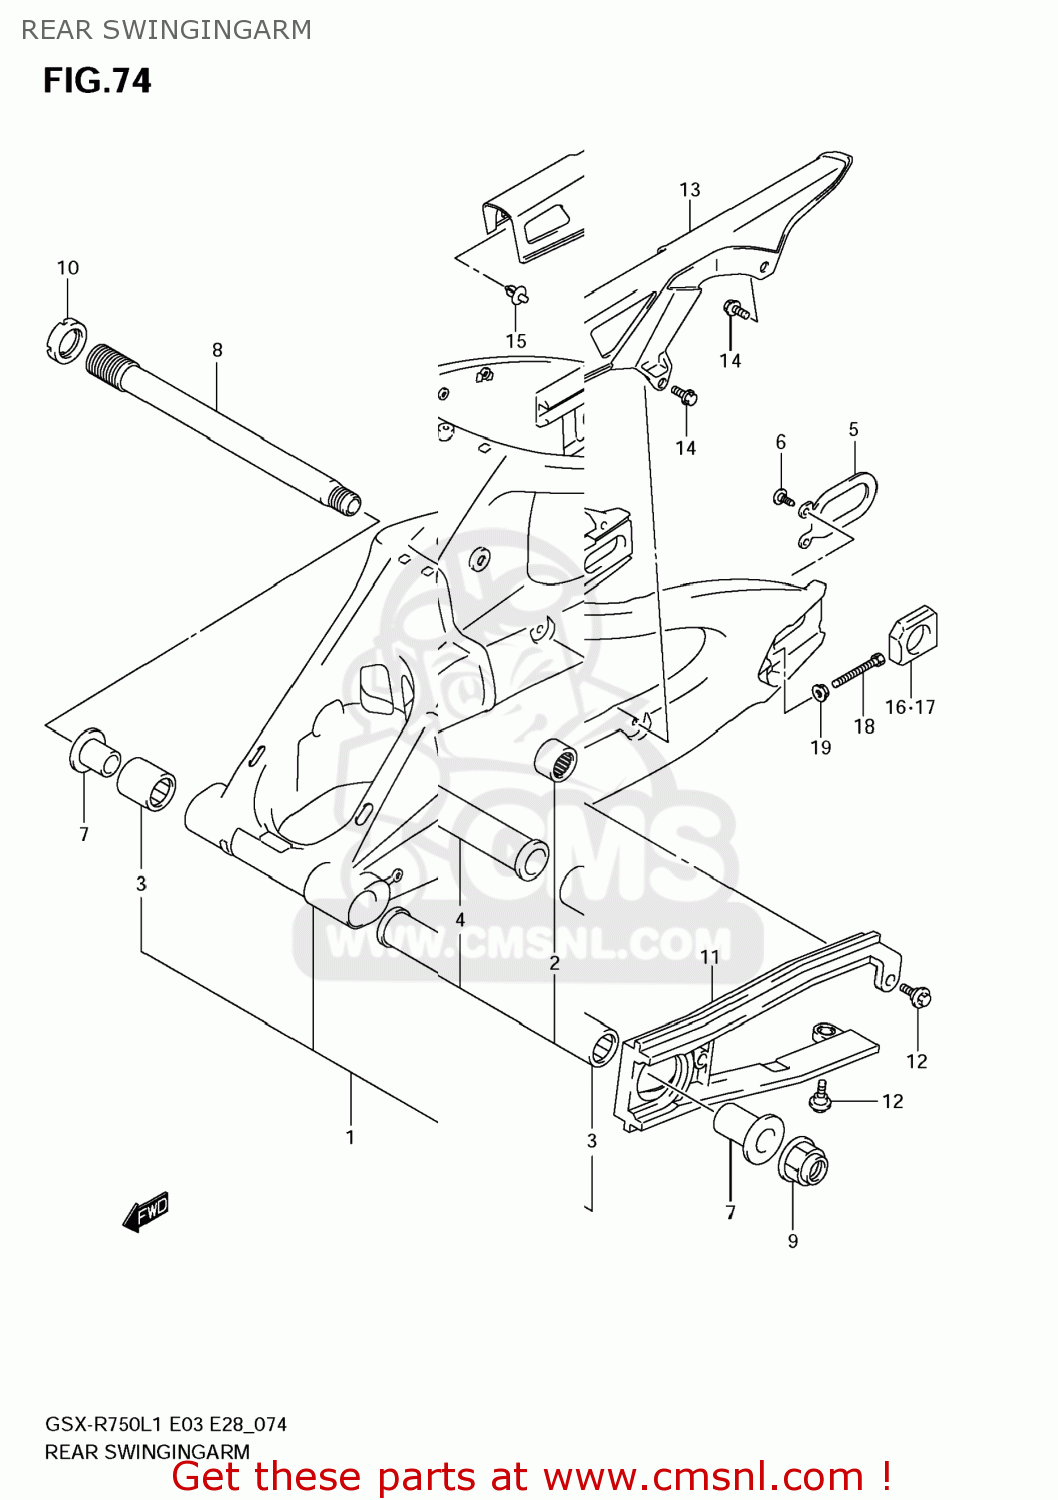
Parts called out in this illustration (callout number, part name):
1	SWINGINGARM ASSY,RR
2	BEARING(20X27X30)
3	BEARING(27X35X35)
4	SPACER,RR SWG PVT CTR
5	PLATE,RR SWING ARM BRKT
6	SCREW(6X12)
7	SPACER,RR SWGARM PIVOT BEARING
8	SHAFT,RR SWINGINGARM PIVOT
9	NUT
10	NUT,REAR SWGAR
11	BUFFER,CHAIN TOUCH DEFENSE
12	BOLT(6X17.8)
13	CASE,CHAIN
14	BOLT(6X12)
15	CLIP(BLACK)
16	ADJUSTER,CHAIN,R
17	ADJUSTER,CHAIN,L
18	BOLT(8X50)
19	NUT
